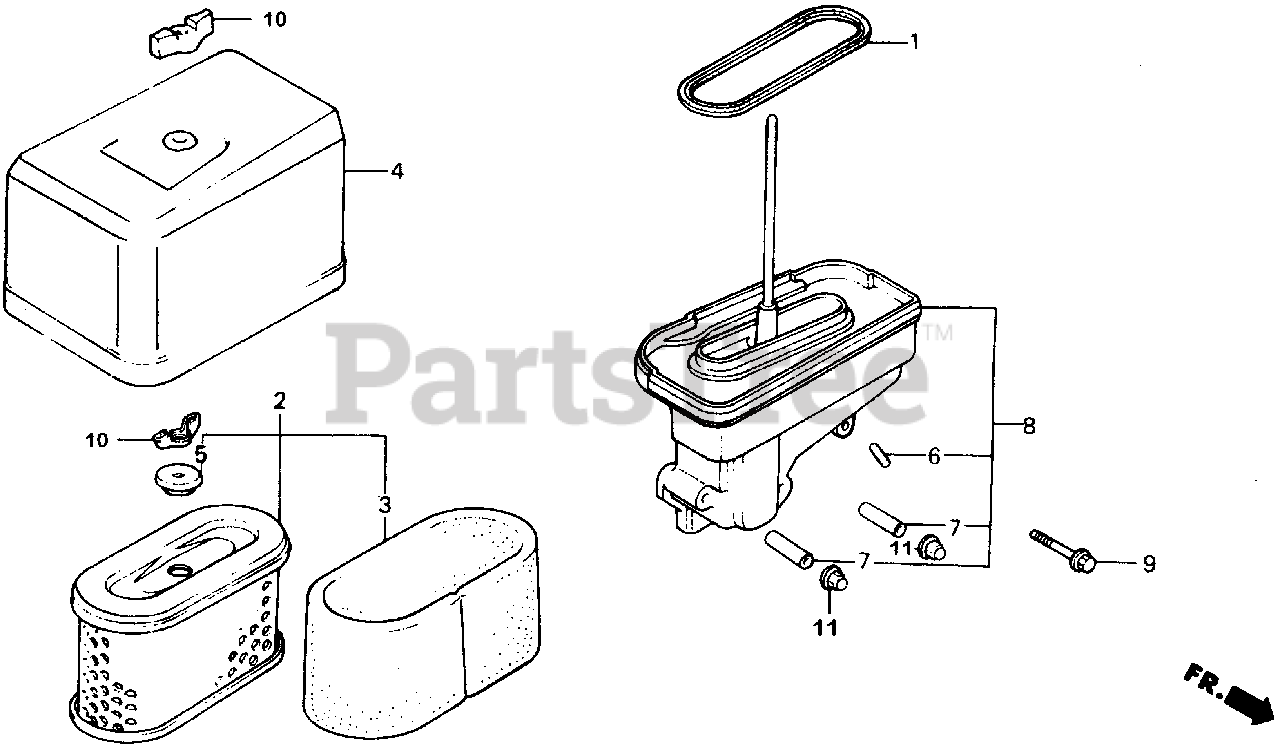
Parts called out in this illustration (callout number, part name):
1	GASKET, ELBOW
2	ELEMENT, AIR CLEANER (METAL BASE)
2	ELEMENT, AIR CLEANER (PLASTIC BASE)
3	FILTER (OUTER)
4	COVER, AIR CLEANER (DUAL)
4	COVER, AIR CLEANER
5	GROMMET, AIR CLEANER
6	COLLAR, AIR CLEANER
7	COLLAR, AIR CLEANER
8	ELBOW, AIR CLEANER
9	BOLT, FLANGE (6X35) (CT200)
10	NUT, TOOL BOX SETTING
11	NUT, FLANGE (6MM)
